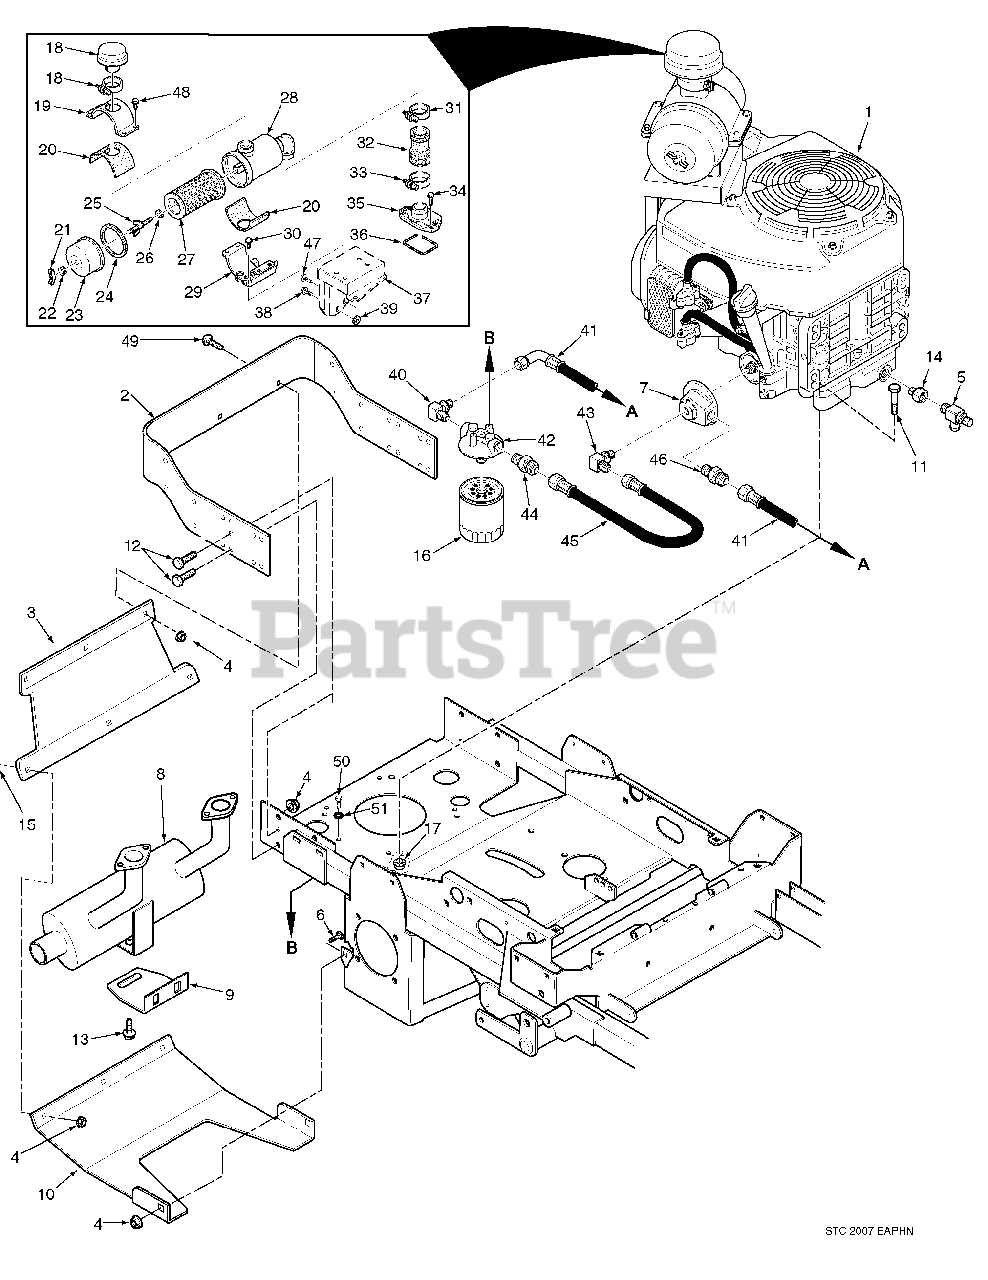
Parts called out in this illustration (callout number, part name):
1	Engine
2	Bumper, Rear
3	Shield, Rear
4	Nut, Serr. Flange 3/8-16
5	Extension, Oil Drain 2.3"
6	Bolt, Carr. 3/8-16 x 1"
7	Adapter, Oil Filter
8	Muffler, Honda
9	Bracket, Muffler
10	Plate, Skid
11	Bolt, Hex Head 5/16-18 x 1-1/2"
12	Bolt, Hex Head 3/8-16 x 1"
13	Screw, 5/16-18 x 3/4" Self Tapping
14	Adapter, M20 x 1.5 / 3/8-18
15	Bolt, Carr. 3/8-16 x 3/4"
16	Oil Filter
17	Nut, Serr. Flange 5/16-18
18	Pre-Cleaner, Engine Air
19	Holder, Air Cleaner Upper
20	Rubber, Air Cleaner Holder
21	Wing Nut - 16mm
22	Grommet, Air Cleaner
23	Cover, Air Cleaner
24	Seal, Air Cleaner
25	Bolt, Air Cleaner
26	Washer, Air Cleaner
27	Element, Air Cleaner
28	Housing, Air Cleaner
29	Holder, Air Cleaner Lower
30	Bolt, Flange
31	Band, Air Cleaner Connecting Tube
32	Tube, Air Cleaner Connecting
33	Band, Air Cleaner Connecting Tube
34	Bolt, Flange
35	Joint B, Connecting Tube
36	Seal, Air Cleaner Housing
37	Stay, Engine Air Cleaner
38	Bolt, Flange
39	Collar, Seat
40	Elbow, 90 Degree 3/8 - 3/8
41	Hose, Remote Oil Filter Inlet
42	Filter Head
43	Elbow, 90 Degree 3/8 - 3/8
44	Tube, Union 1/2 - 3/8
45	Hose, Remote Oil Filter Return
46	Tube, Union 1/2 - 3/8
47	Bolt, Flange
48	Bolt, Flange
49	Bolt, 3/8-16 x 1" Torx
50	Bolt, Hex Head 1/4-20 x 5/8"
51	Lockwasher, 1/4" Spring
